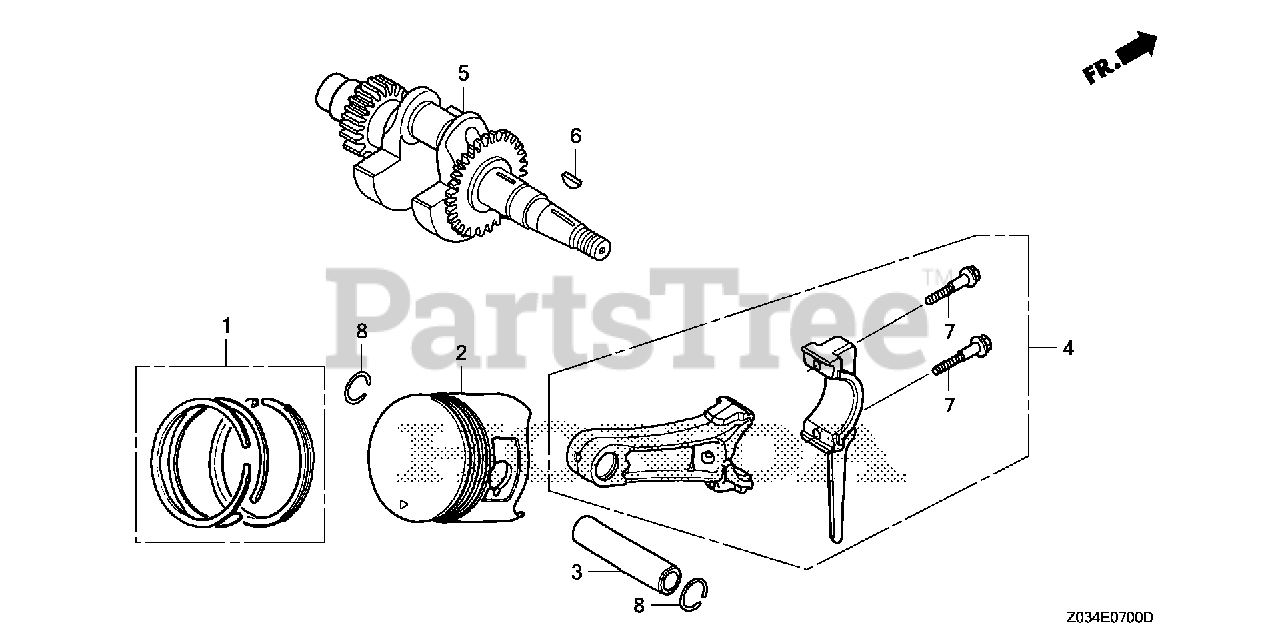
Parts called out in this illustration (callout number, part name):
1	RING SET, PISTON (STD) (TPR)
1	RING SET, PISTON (0.25) (TPR)
1	RING SET, PISTON (0.50) (TPR)
1	RING SET, PISTON (0.75) (TPR)
1	RING SET, PISTON (STD) (RIKEN)
1	RING SET, PISTON (0.25) (RIKEN)
1	RING SET, PISTON (0.50) (RIKEN)
1	RING SET, PISTON (0.75) (RIKEN)
2	PISTON (STD)
2	PISTON (0.25)
2	PISTON (0.50)
2	PISTON (0.75)
3	PIN, PISTON
4	ROD ASSY., CONNECTING (TH)
4	ROD ASSY., CONNECTING (UNDER SIZE)
5	CRANKSHAFT
6	KEY, SPECIAL WOODRUFF (25X18)
7	BOLT, CONNECTING ROD
8	CLIP, PISTON PIN (18MM)
